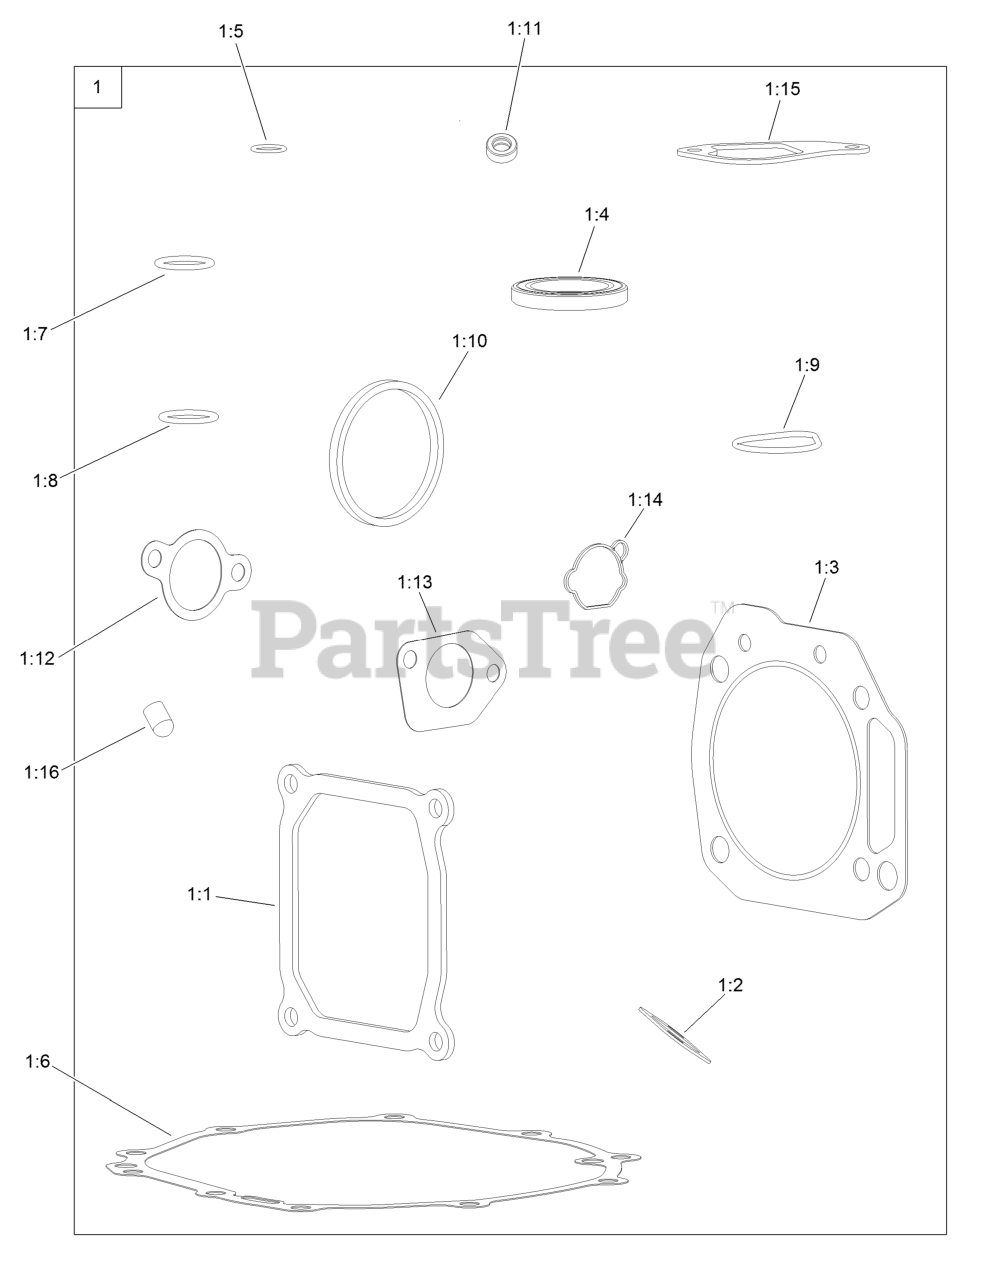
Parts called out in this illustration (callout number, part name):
1	Gasket And Seal Kit
1:1	Gasket-Cover, Valve
1:2	Gasket-Exhaust
1:3	Gasket-Cyclinder
1:4	Seal-Oil
1:6	Gasket-Crankcase
1:9	Seal-Pump, Oil
1:10	Seal-Adaptor, Oil
1:11	Seal-Oil
1:12	Gasket-Carburetor
1:13	Gasket-Carburetor
1:14	Gasket-Carburetor
1:15	Gasket-Breather
1:16	Cap-Seal
